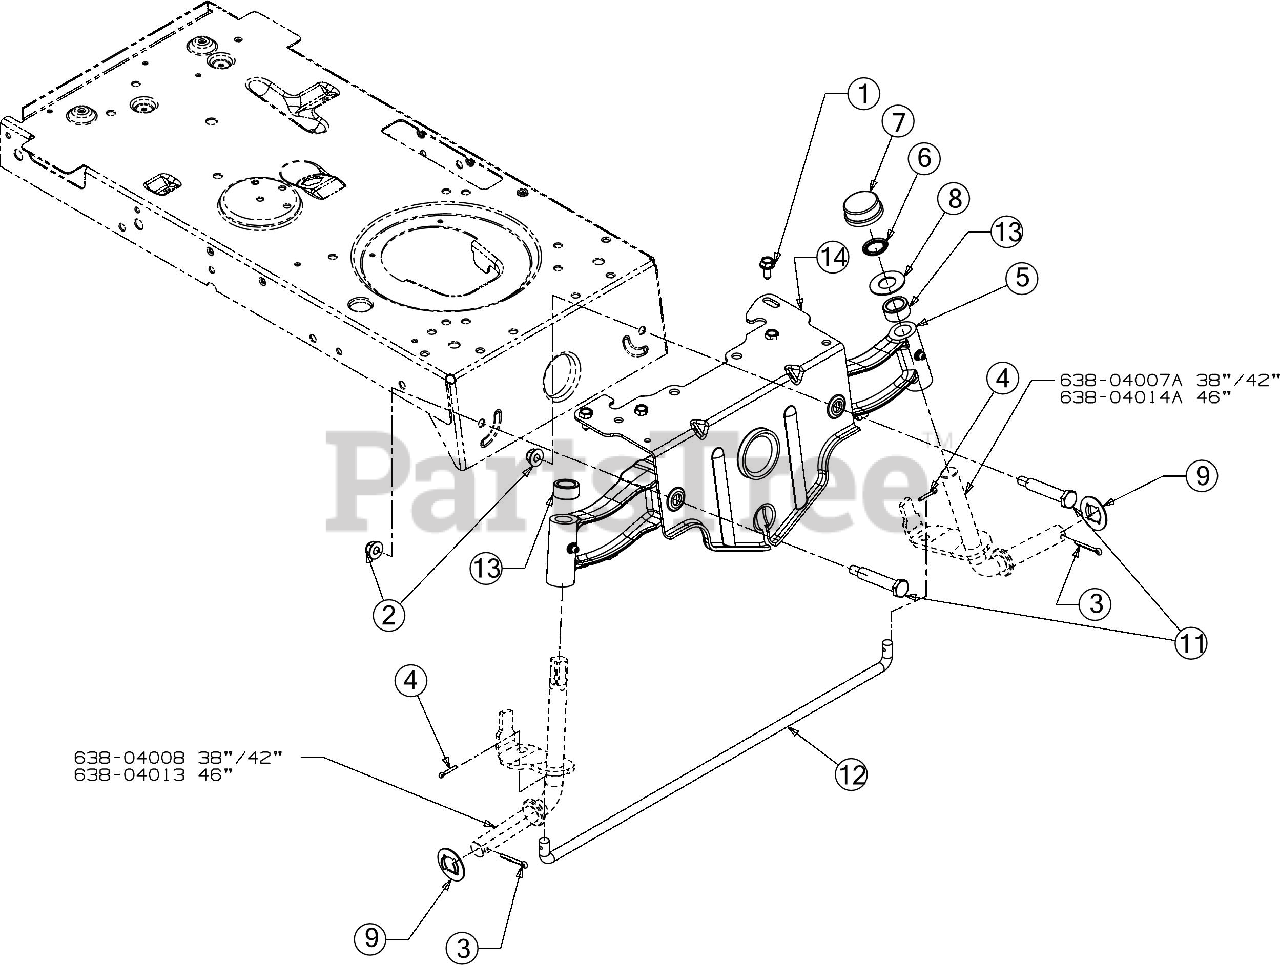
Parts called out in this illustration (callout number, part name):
1	SCREW 5/16-18 x .750
3	COTTER PIN-5/32 DIA
4	COTTER PIN
5	PIVOT BAR AXLE
6	PUSH NUT, 3/4" ID
8	FLAT WASHER
9	FLAT WASHER .781 ID x1.590 OD
10	GREASE-#251 EP (NOT SERVICEABLE)
11	SHOULDER SCREW .500X2.38X3/8-16
12	FIXED TIE ROD
13	SPACER .77IDX1.130ODX.56
14	PIVOT BAR BRACKET
